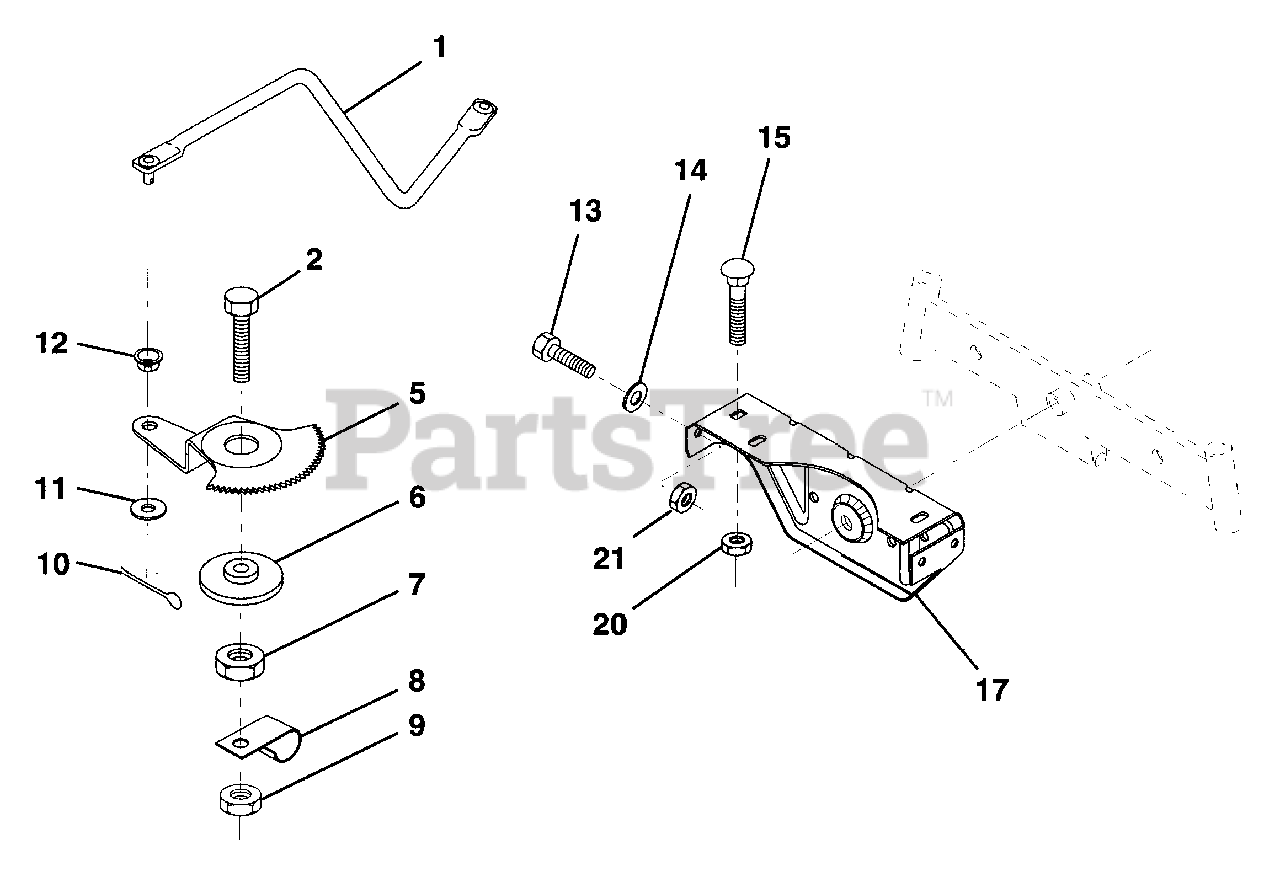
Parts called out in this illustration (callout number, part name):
1	Link, Drag
2	Bolt, Hex, Fin. 1/2-13 x 1-3/4
5	Gear, Sector
7	Nut, Heavy Hex, Top Lock 1/2-13 UNC
8	Clip, Insulated
9	Nut, Crownlock 3/8-16
10	Pin, Cotter 1/8 x 3/4
11	Washer 13/32 x 13/16 x 16 Gauge
13	Bolt, Hex Head 5/16-18 UNC x 1
14	Washer 11/32 x 7/8 x 16 Gauge
15	Bolt, Carriage 3/8-16 UNC x 3/4
17	Support, Front Axle
20	Nut, Crownlock 3/8-16
21	Nut, Hex, Crownlock 5/16-18
